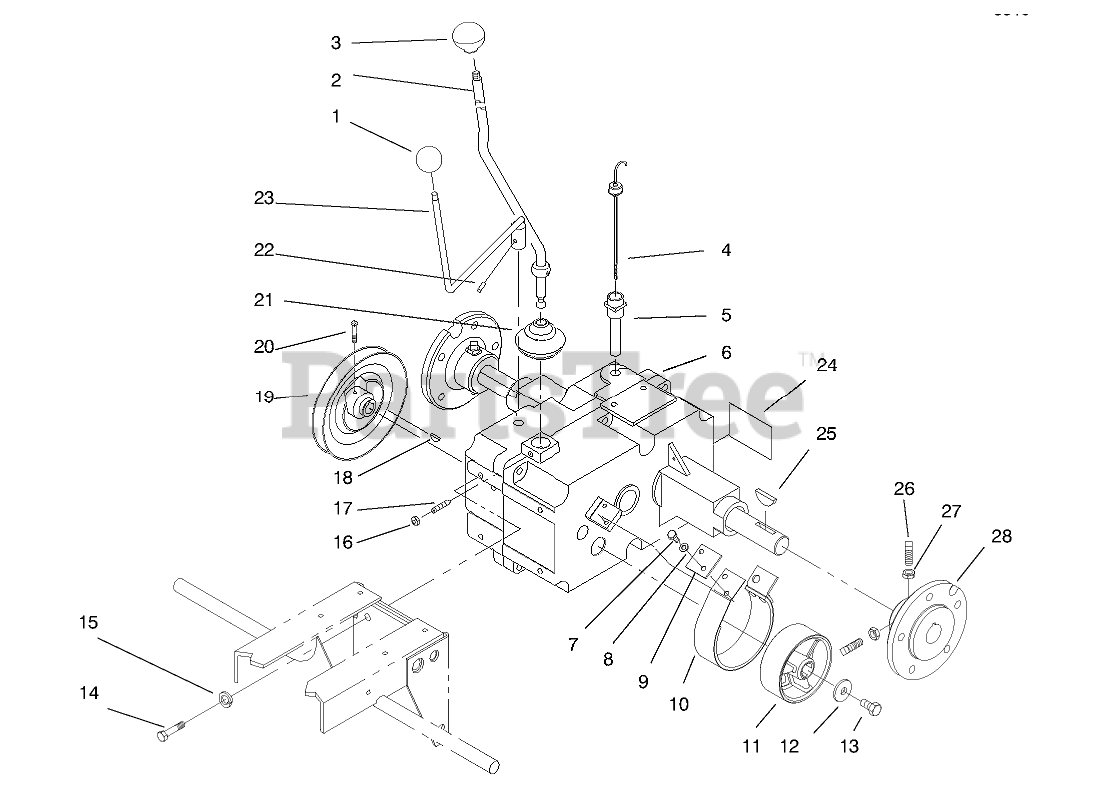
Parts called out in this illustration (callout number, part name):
2	ASM-Rod
4	DIPSTICK
5	NIPPLE-FILL, TRANSMISSION
6	TRANSMISSION ASM
7	SCREW-HH
8	WASHER-LOCK
9	Plate-Stop
10	BRAKE BAND ASM
11	DRUM-BRAKE
12	WASHER
13	SCREW-HEX HD CAP
14	SCREW-HH
15	WASHER-LOCK
16	NUT-HEX
17	SETSCREW
18	KEY-HI PRO
19	PULLEY-TRANSMISSION
20	SCREW-SQH
21	COVER-DUST
22	PIN-SPIROL
23	SHIFT ROD ASM
24	DECAL-UNIDRIVE
25	KEY-WOODRUFF
26	SCREW-SET, SQH
27	NUT-JAM
28	HUB-WHEEL
